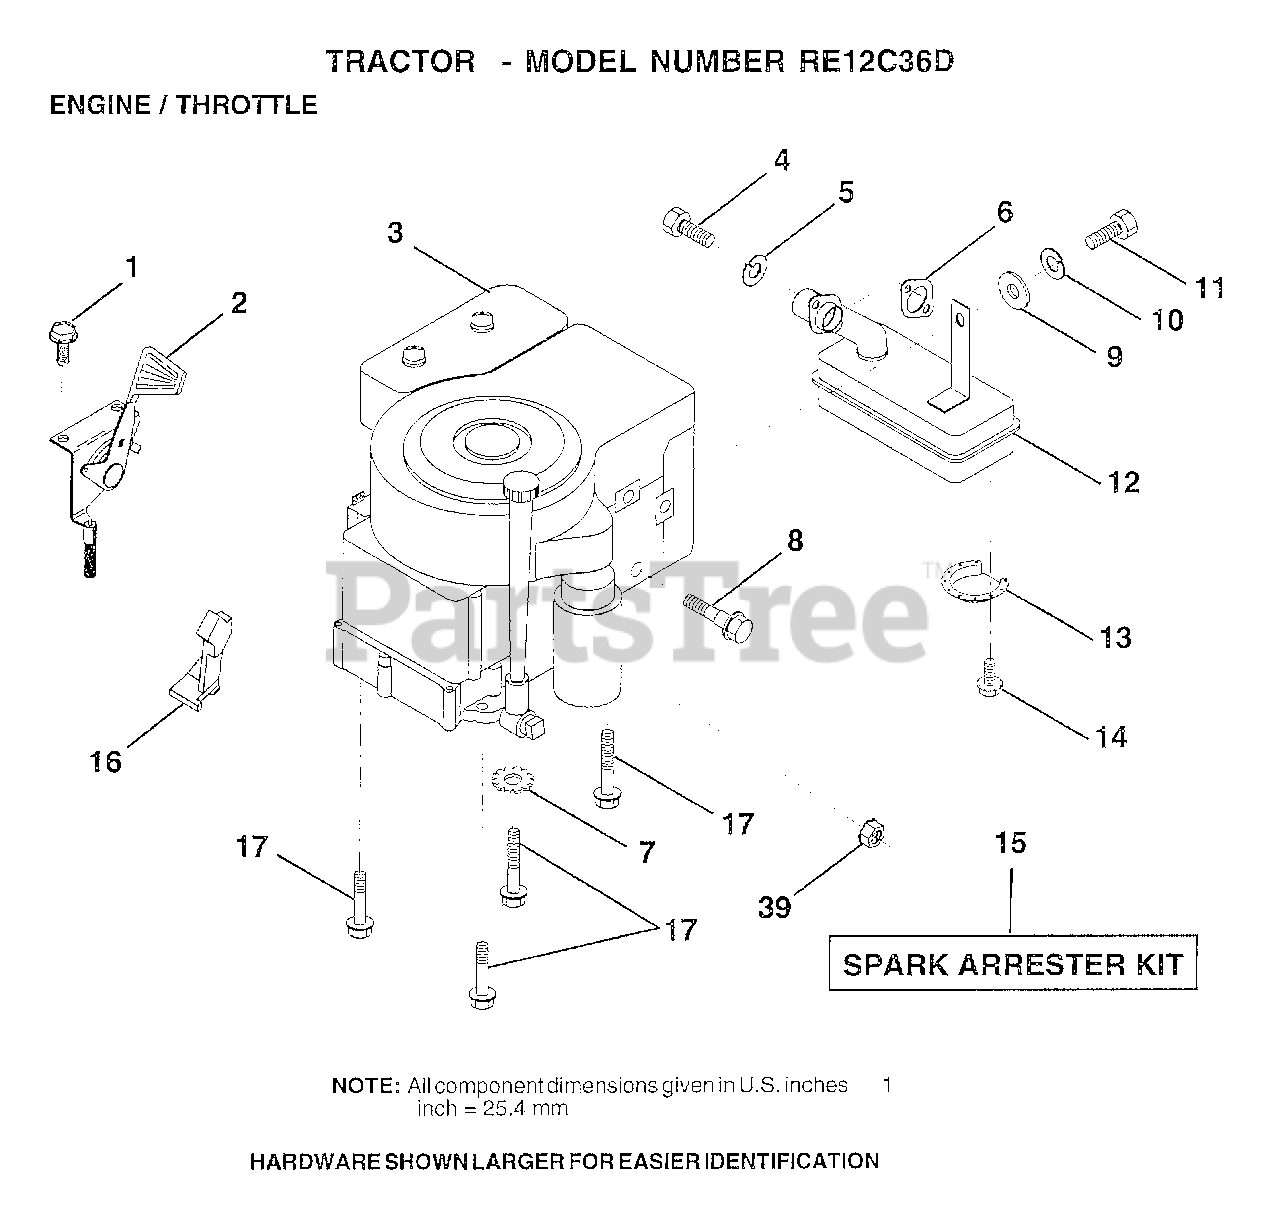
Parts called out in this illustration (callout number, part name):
1	SCREW LT
4	SCREW
5	LOCKWASHER
7	LOCKWASHER
8	BOLT T
10	LOCKWASHER
12	MUFFLER
13	DEFLECTOR.222573
16	"STOP,DASH THROTT"
17	SCREW LT
39	NUT
